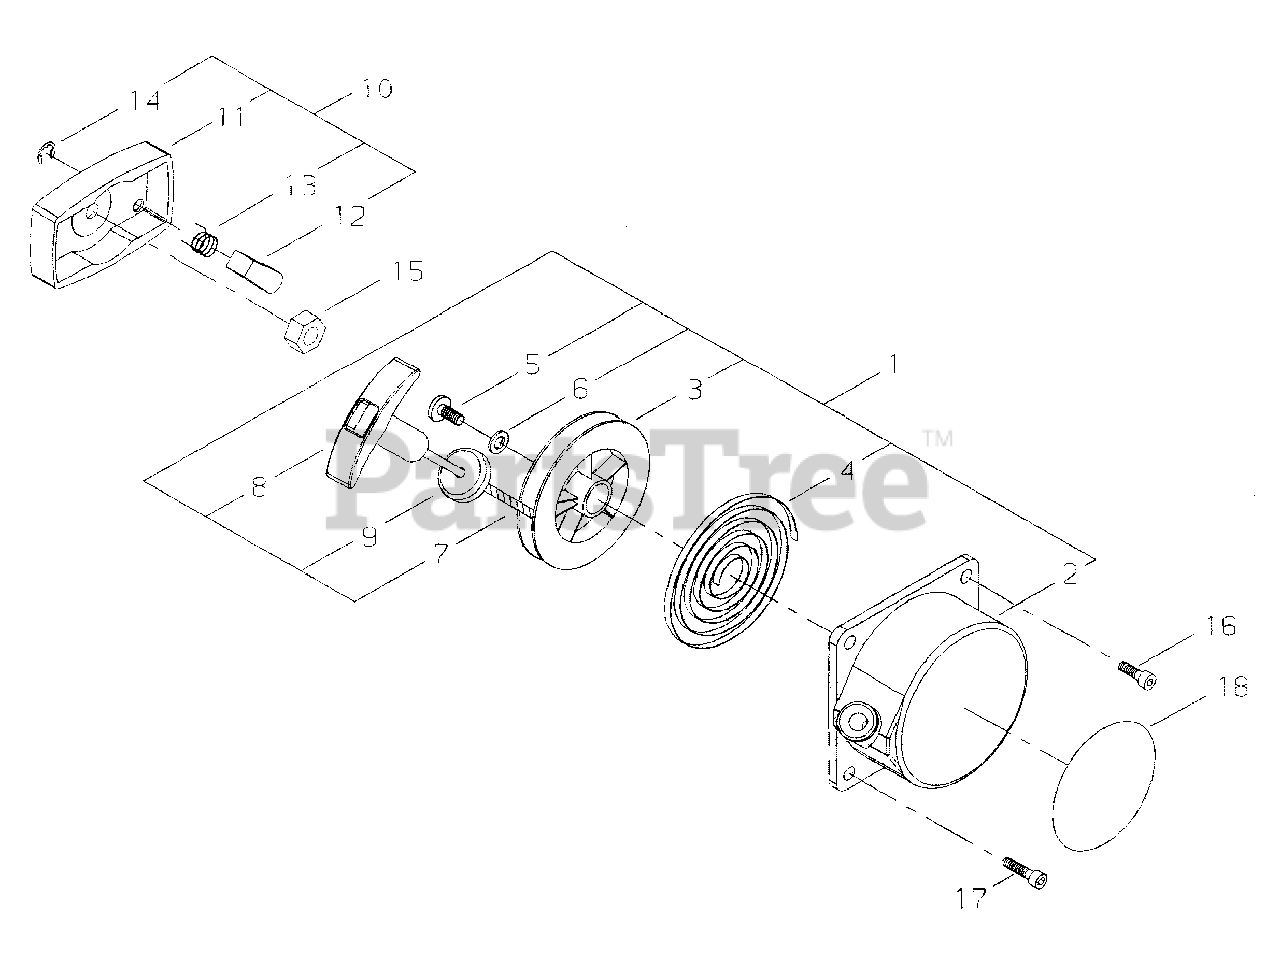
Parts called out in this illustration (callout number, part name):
1	STARTER ASSY, RECOIL
2	CASE, RECOIL STARTER
3	REEL, ROPE
4	SPRING, RECOIL
5	SCREW 5
6	WASHER
7	ROPE, STARTER
8	GRIP, STARTER
9	DAMPER
10	PULLEY ASSY, STARTER
11	PULLEY, STARTER
12	PAWL, STARTER
13	SPRING, RETURN
14	E-RING 4
15	NUT
16	BOLT M5×20
17	BOLT M5×25
18	LABEL, TRADE (RED)
